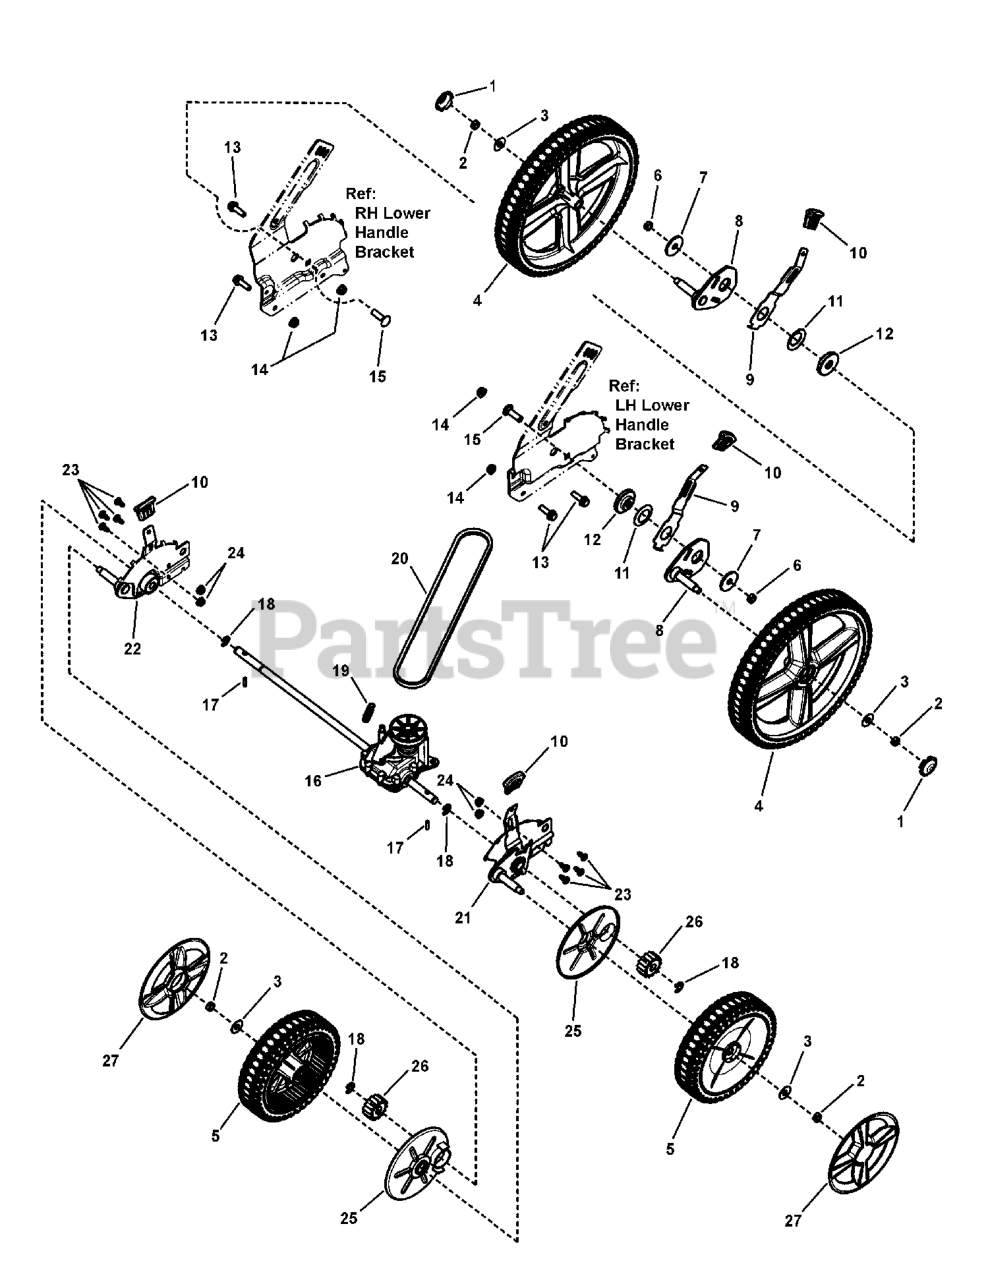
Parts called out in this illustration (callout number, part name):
1	HUBCAP, 12" Rim Yellow
2	NUT, 3/8-16 Hex Center Lock Jam, YZ
3	WASHER, 1" OD x .387 ID Flat
4	WHEEL,12" x 2" Idle, w/Db Tread, Brute Yellow
5	WHEEL, 8" x 2" Drive, w/DB Tread P-290 Satin Black
6	NUT, 3/8-16 Hex Center Lock, YZ
7	WASHER, 13/32 x 1-1/2" x .120 Flat, YZ
8	ASSEMBLY, Wheel Bracket, Rear, High-Wheel (staked)
9	LEVER, Front, Height-Of-Cut, 22"
10	GRIP, Height Latch, P-391-St, Yellow
11	WASHER, 1" ID x 1.64 OD Bellville
12	BUSHING, Pivot, Hi-Wheel, Rear
13	BOLT, 5/16-18 x 1" Hex Flange Lock, GR 5, YZ
14	NUT, 5/16-18 Hex Flange Lock, GR 5, YZ
15	BOLT, 3/8-16 x 1-1/4" Round Head Square Neck Carriage, GR 5 YZ
16	TRANSMISSION, Single Speed, Front Wheel Drive
17	PIN, Drive, 22" WBM, Front Wheel Drive
18	RETAINING RING
19	SPRING, Tension, Front Wheel Drive, Single Speed
20	BELT, Drive, 22" WBM, Front Wheel Drive
21	ASSEMBLY, Height-Of-Cut, LF, 22" WBM, Propelled
22	ASSEMBLY, Height-Of-Cut, RF, 22" WBM, Propelled
23	SCREW, 1/4-20 x .550 Pan Head Torx (T-30)
24	NUT, 1/4-20 Hex Flange Lock, YZ
25	SHIELD, Dust, 22" WBM, Front Wheel Drive
26	GEAR, Pinion, 22" WBM, Front Wheel Drive
27	HUBCAP, 8"& 9" Wheel Spoked, P-391 St Yellow
